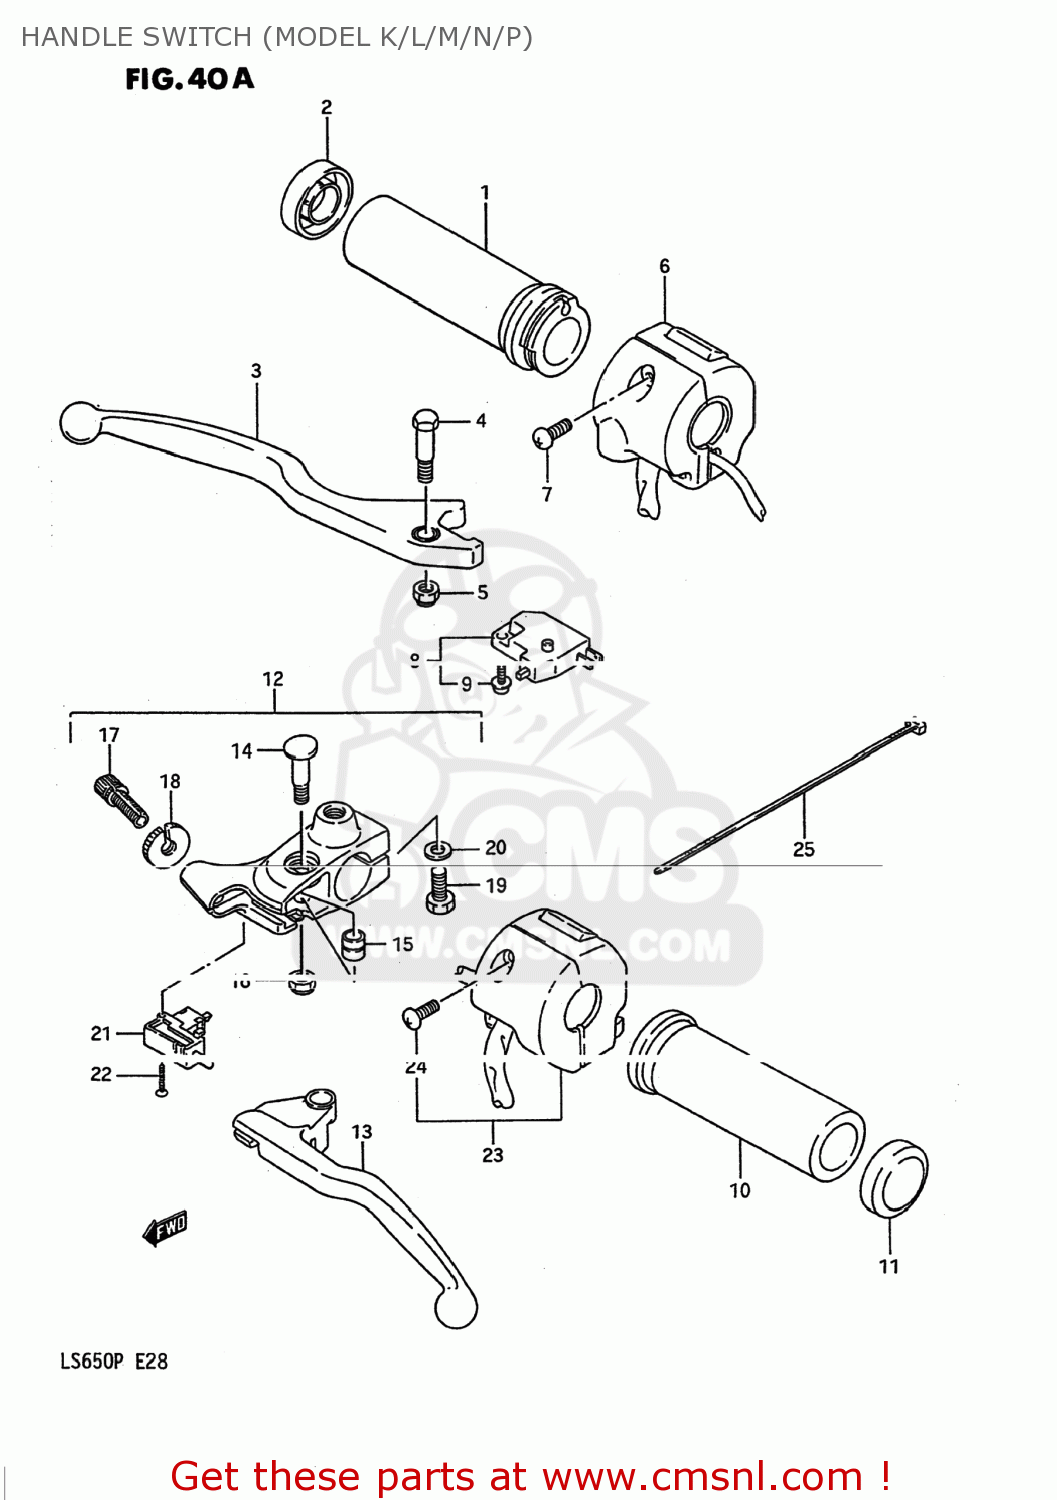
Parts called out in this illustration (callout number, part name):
1	GRIP,THROTTLE
2	CAP,GRIP END
3	LEVER,BRAKE
4	BOLT,LEVER
5	NUT 6MM
6	SWITCH ASSEMBLY,HANDLE,RIGHT
7	SCREW
8	SWITCH ASSEMBLY,STOP
9	SCREW
10	GRIP,L
11	CAP,GRIP END
12	LEVER ASSEMBLY
13	LEVER,CLUTCH
14	BOLT,CLUTCH LEVER
15	SPACER,CLUTCH LEVER PIVOT
16	NUT 6MM
17	ADJUSTER,WIRE
18	NUT,LOCK
19	BOLT
20	WASHER
21	SWITCH,CLUTCH
22	SCREW
23	SWITCH ASSY,HANDLE,L
24	SCREW
25	CLAMP
